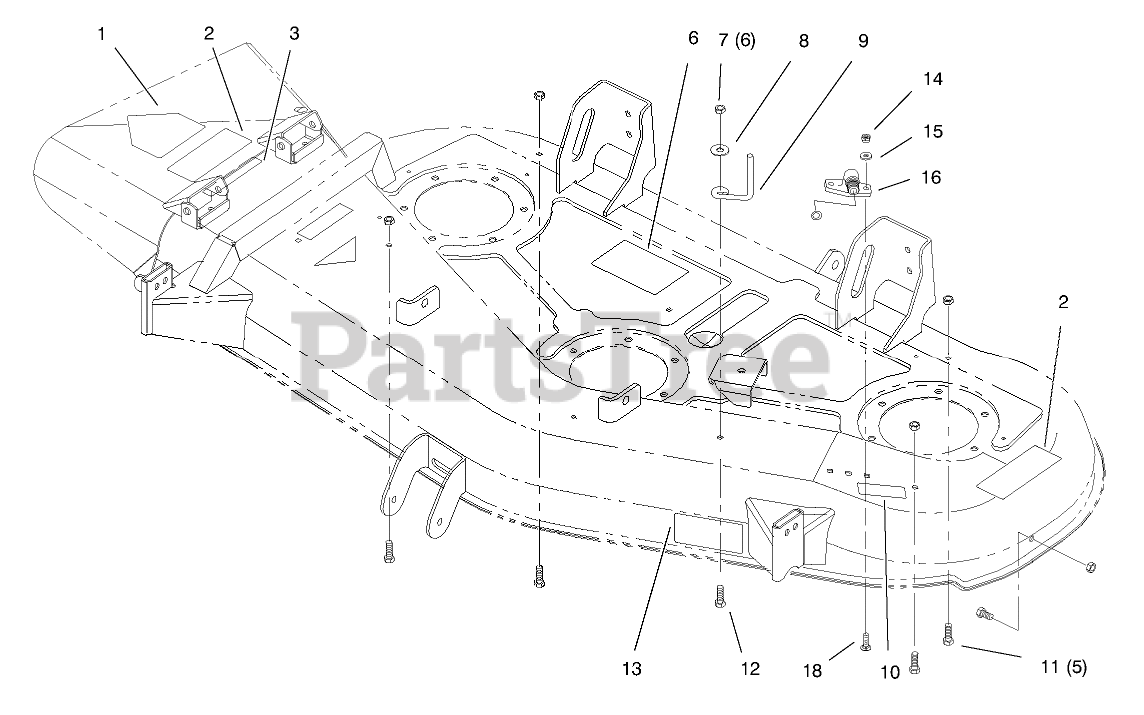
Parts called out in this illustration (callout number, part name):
1	DECAL-DANGER
2	DECAL-DANGER
3	DECAL-DANGER
6	DECAL-BELT ROUTING
7	NUT-LOCK, NI
8	WASHER-PLAIN
9	GUIDE-BELT
10	DECAL-BELT ROUTING
11	SCREW-HH
12	SCREW-HH
13	DECAL-ADJUSTMENT, WHEEL
14	NUT-LOCK, NI
15	WASHER-FLAT
16	FITTING-WASHOUT
17	O-RING
18	BOLT-CARR
